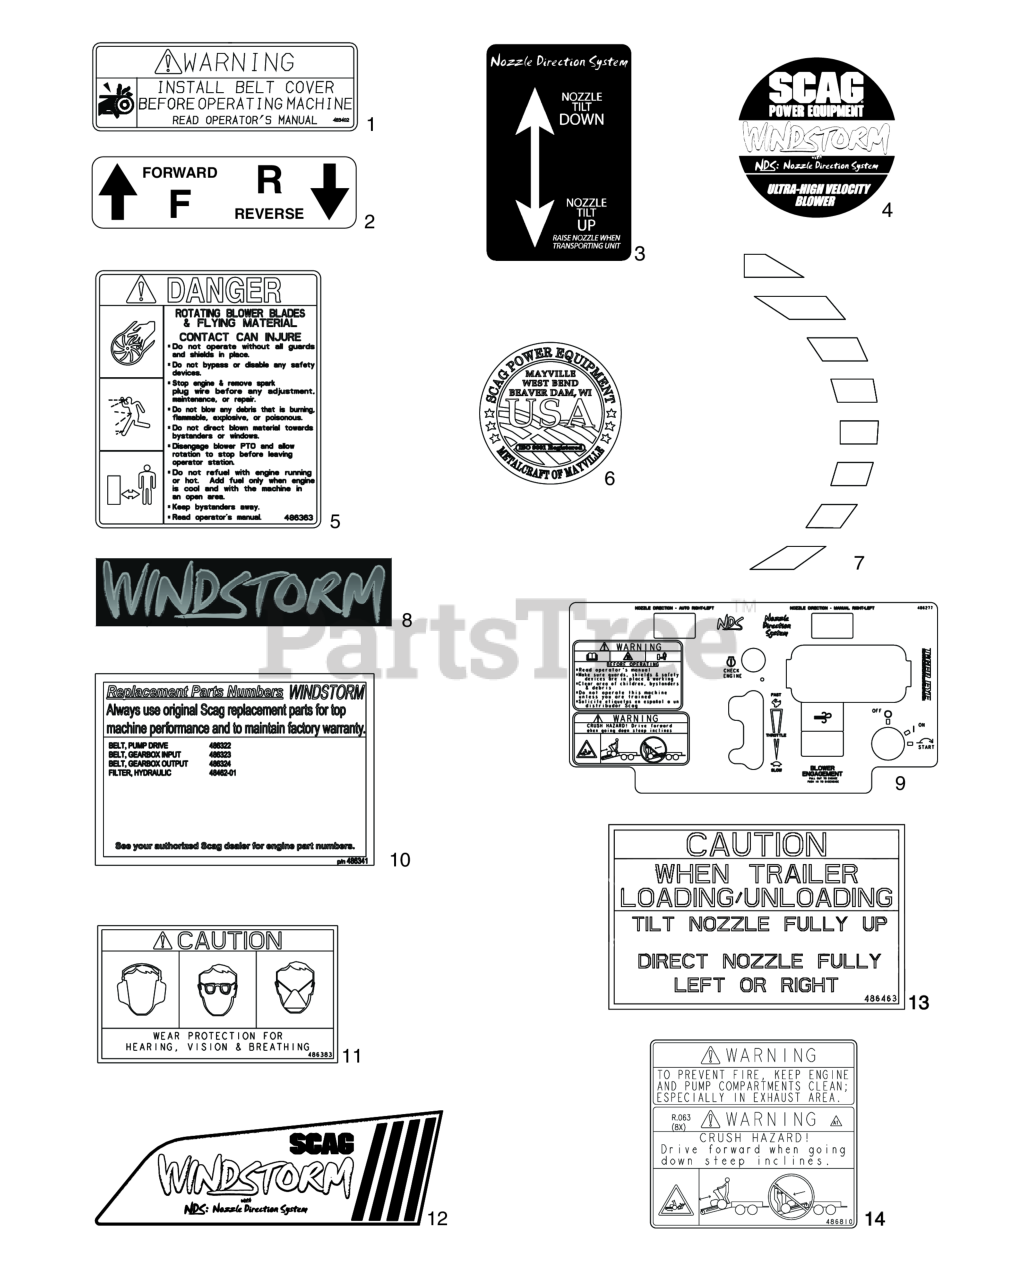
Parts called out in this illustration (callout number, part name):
1	Decal, Warning - Belt Cover
2	Decal, Traction Control
3	Decal, Nozzle Tilt
4	Decal, Front-Windstorm
5	Decal, Danger-Blower
6	Decal, Metalcraft - USA
7	Decal, Housing-Front
8	Decal, Housing-Side
9	Decal, Instrument Panel
10	Decal, Windstorm Replacement Parts
11	Decal, Personal Protection
12	Decal, Windstorm Tank
13	Decal, Trailer Loading
14	Decal, Burn Hazard
